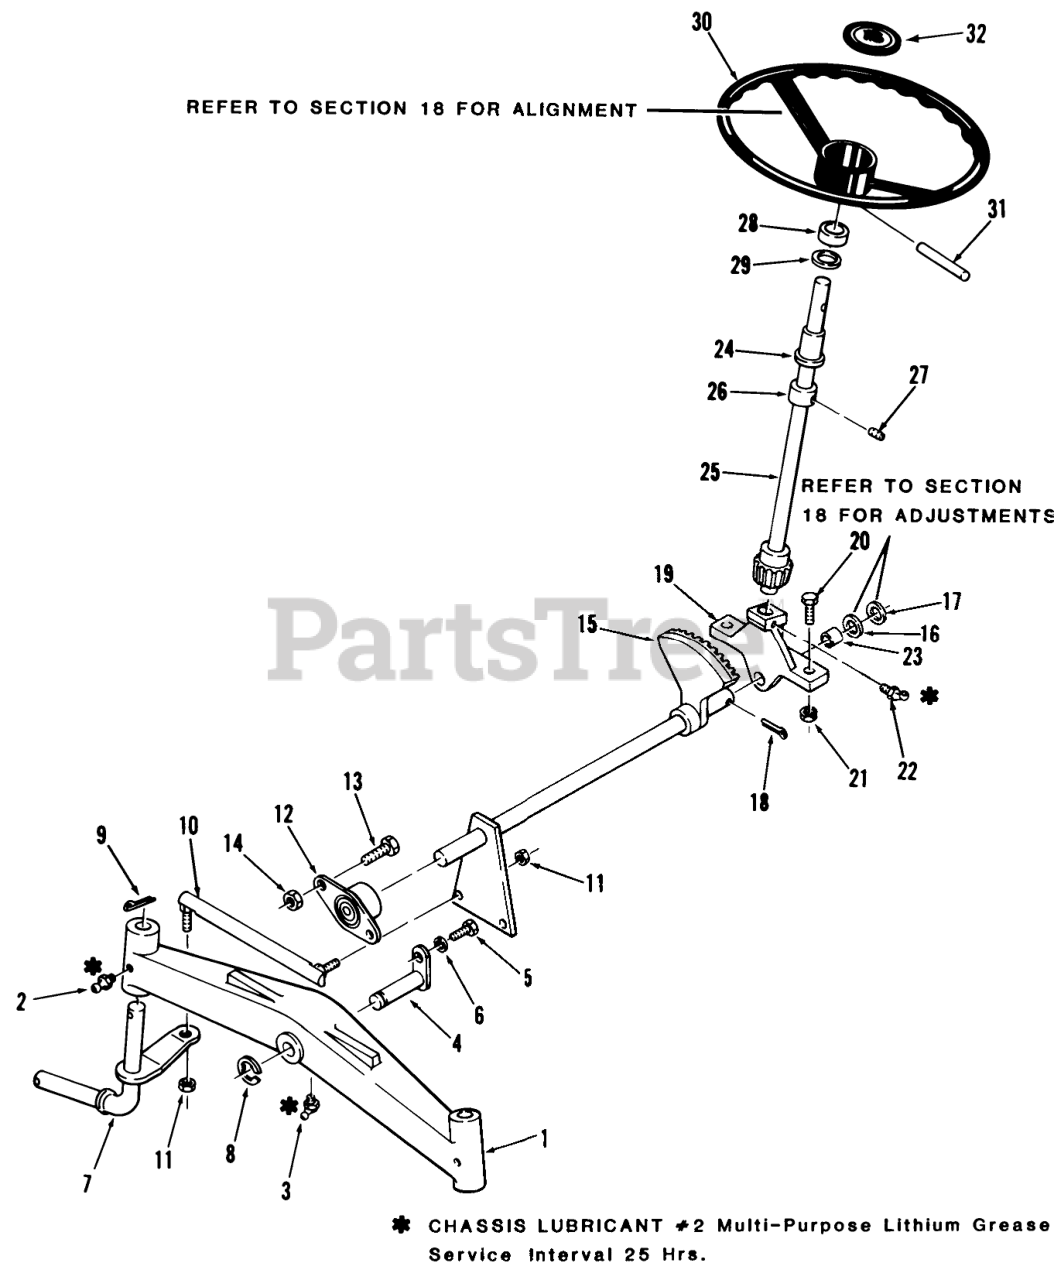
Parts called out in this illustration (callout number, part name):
1	AXLE-FRONT
2	Zerk
3	FITTING-GREASE
4	PIN AND PLATE ASM
5	H H C S
6	Lockwasher
7	Front Spindle RH
7	Front Spindle LH
8	E-RING
9	COTTER PIN-4
10	Tie Rod RH
10	Tie Rod LH
11	NUT-6
12	BEARING-FLANGED
13	Bolt
14	Nut
15	Assy-Steering
16	WASHER-SHIM
17	WASHER
18	PIN-4
19	Support
20	BOLT
21	Nut
22	FITTING-GREASE
23	BEARING-BRONZE
24	BEARING
25	Shaft-Upper Steering
26	Collar
27	SCREW-SET
28	Collar
29	WASHER-BOWED
30	STEERING WH 13" SOFT
31	Pin-Roll
32	STEERING WHEEL INSE
